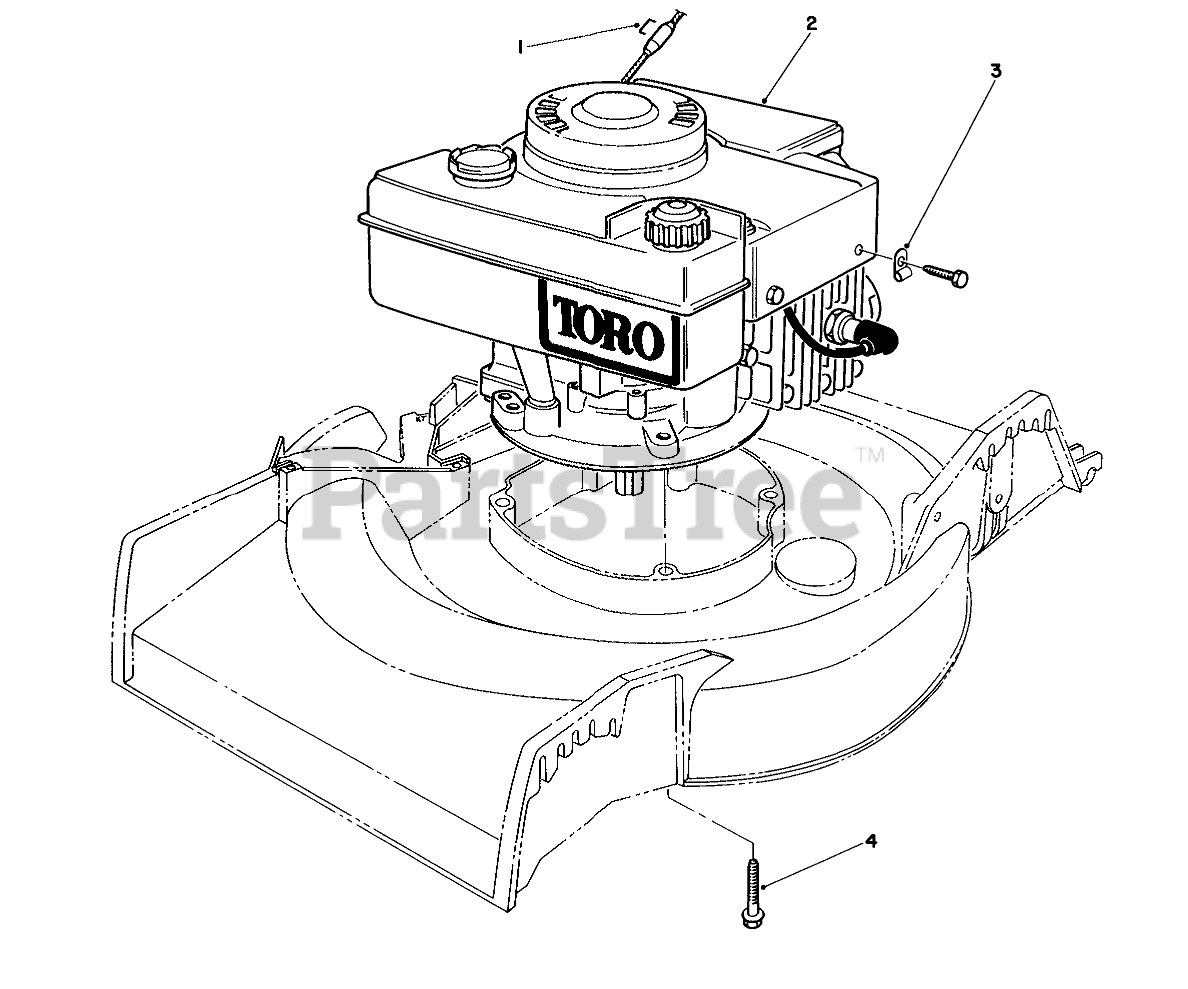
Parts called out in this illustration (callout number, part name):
1	Staple
3	CLAMP
4	3/8-16 X 2-3/4 CAPSCR
